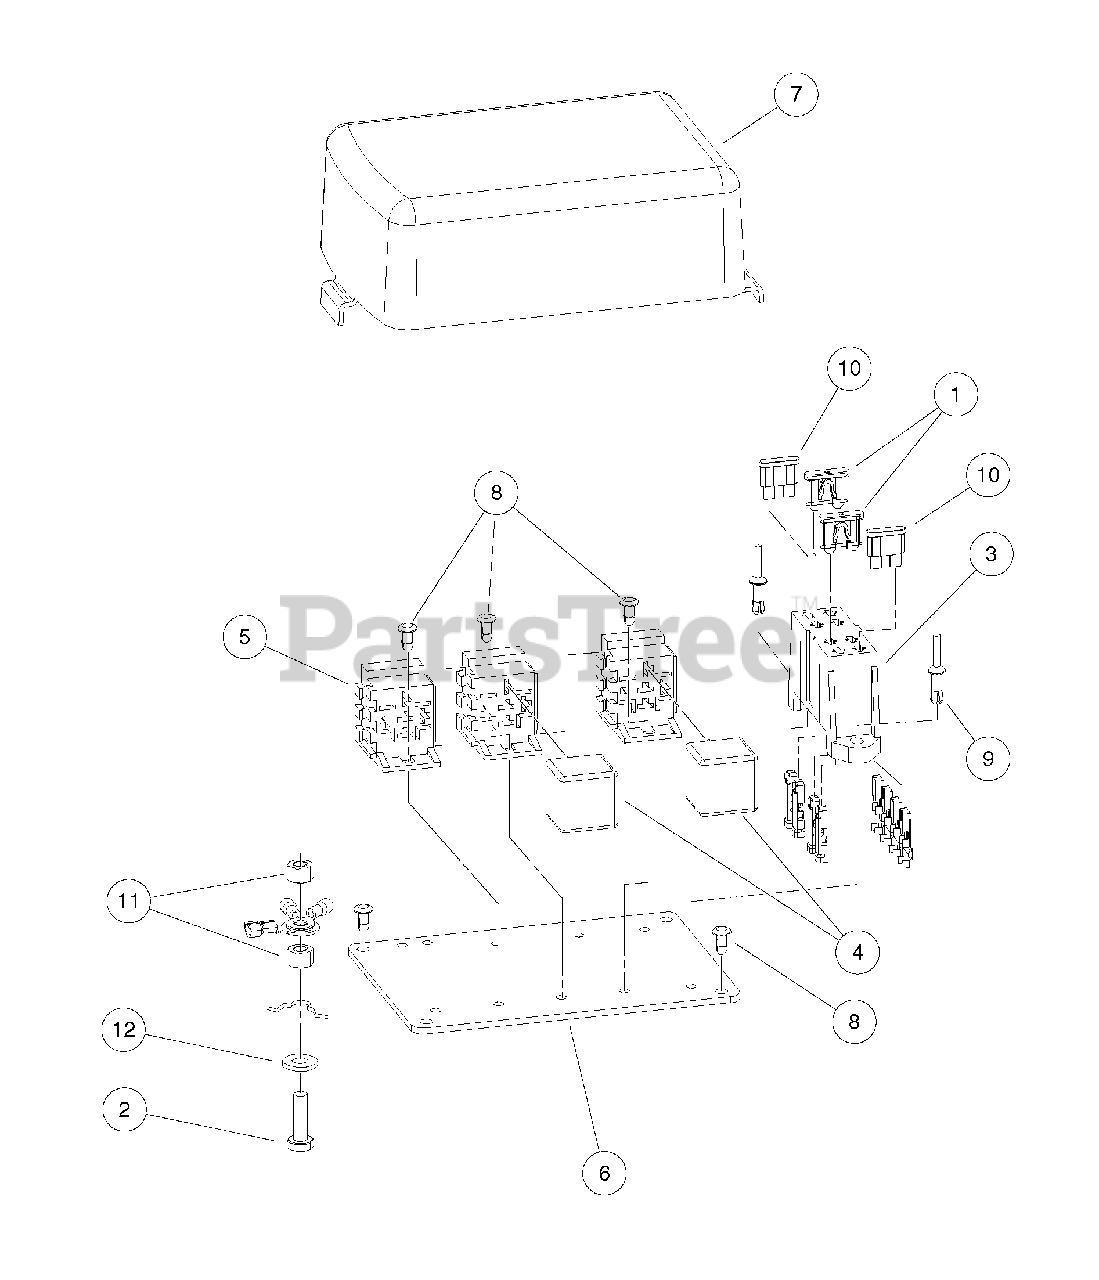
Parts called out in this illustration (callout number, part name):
1	Fuse, 10-Amp
2	Screw, 1/4-20 X .88 Hex Hd Cap
3	Fuse Block
4	Relay, Mini ISO, SPDT
5	Connector, Relay
6	Plate, Electrical
7	Cover, Electrical
8	Fastener, Push-in
9	Rivet, Drive
10	Fuse, 25-Amp
11	Locknut, 1/4-20 Dimpled
12	Washer, 1/4 Type A Narrow Flat
